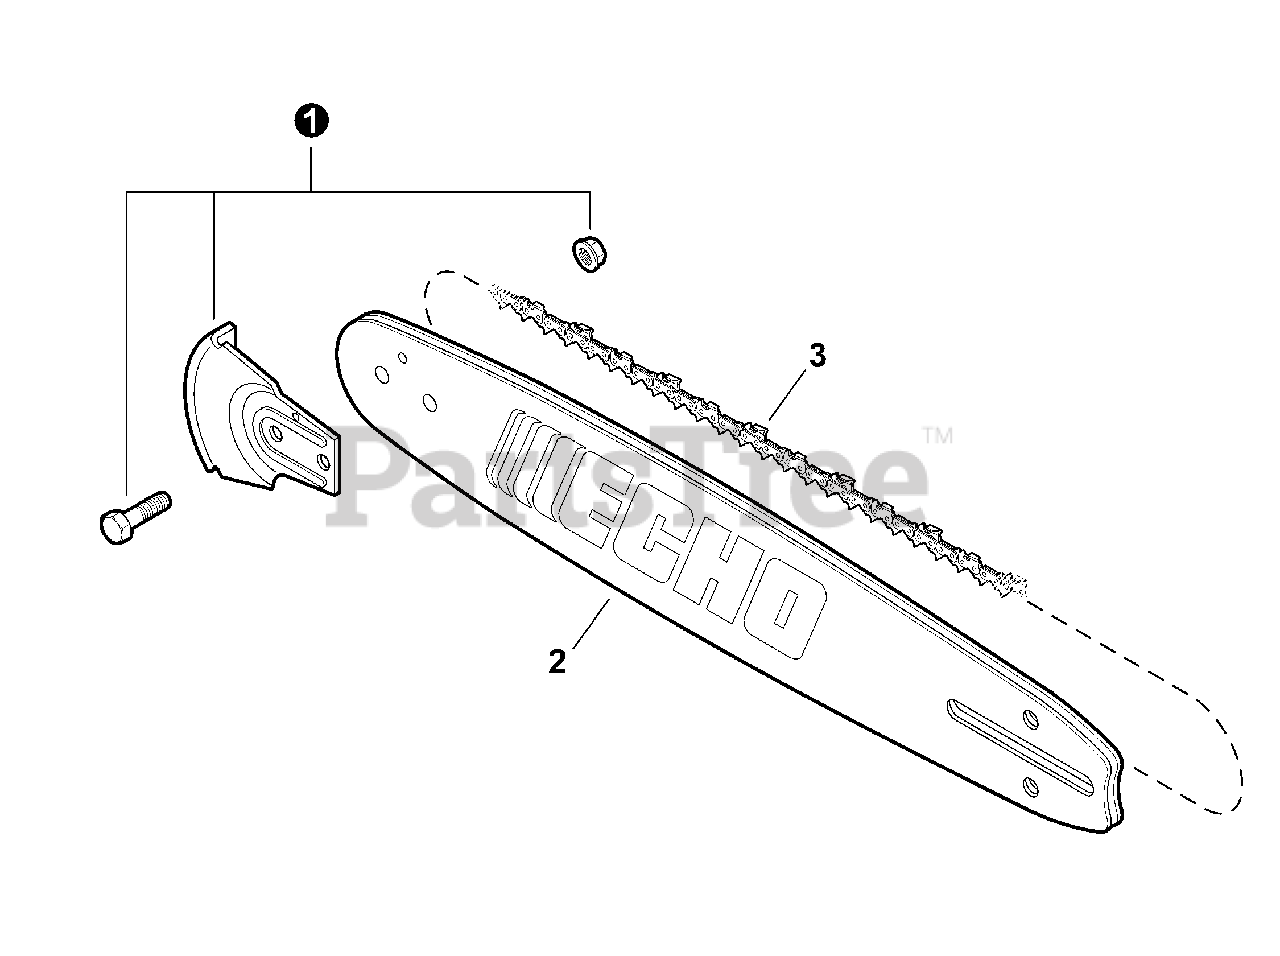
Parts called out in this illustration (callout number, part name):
1	KICK GUARD KIT
2	GUIDE BAR - 16" (40cm)
2	GUIDE BAR - 18" (45cm)
2	GUIDE BAR - 20" (50cm)
2	GUIDE BAR - 24" (60cm)
2	GUIDE BAR - 27" (68cm)
3	SAWING CHAIN - 16" (40cm)
3	SAWING CHAIN - 18" (45cm)
3	SAWING CHAIN - 20" (50cm)
3	SAWING CHAIN - 24" (60cm)
3	SAWING CHAIN - 27" (68cm)
